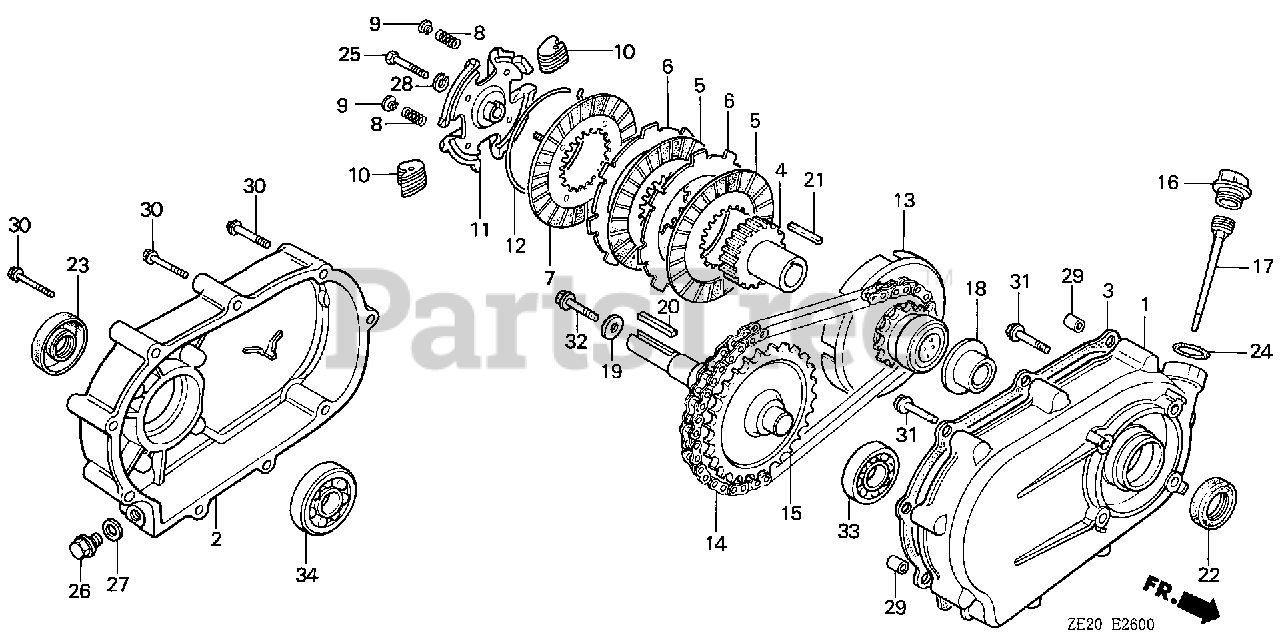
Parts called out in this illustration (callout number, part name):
1	CASE, REDUCTION
2	COVER, REDUCTION
3	GASKET, REDUCTION COVER
4	CENTER, CLUTCH (28T)
5	DISK, CLUTCH FRICTION
6	PLATE, CLUTCH
7	PLATE, CLUTCH PRESSURE
8	SPRING, CLUTCH FREE
9	HOLDER, CLUTCH SPRING
10	WEIGHT, CLUTCH
11	HOLDER, CLUTCH WEIGHT
12	CENTER, CLUTCH WEIGHT
13	SPROCKET, DRIVE (14T)
14	CHAIN, DRIVE (RK428SH-36LE)
15	SHAFT, P.T.O. (28T)
16	CAP, REDUCTION OIL (GRAY)
16	CAP, REDUCTION OIL (YELLOW)
17	DIPSTICK, OIL
18	WASHER, THRUST (25MM)
20	KEY (7X7X33)
20	KEY (7X7X33) (OVER SIZE) (YELLOW)
21	KEY, CLUTCH CENTER
22	OIL SEAL (30X46X8)
23	OIL SEAL (30X50X7)
23	OIL SEAL (PJ30507)
24	O-RING (26X2.7)
25	BOLT, HEX. (8X35)
26	BOLT, DRAIN PLUG (12MM)
27	WASHER, DRAIN PLUG (12MM)
28	WASHER, SPRING (8MM)
29	PIN, DOWEL (8X12)
29	PIN A, DOWEL (8X12)
30	BOLT, FLANGE (6X50)
31	BOLT, FLANGE (8X32)
32	BOLT, FLANGE (8X25)
33	BEARING, RADIAL BALL (6205)
34	BEARING, RADIAL BALL (6206)
